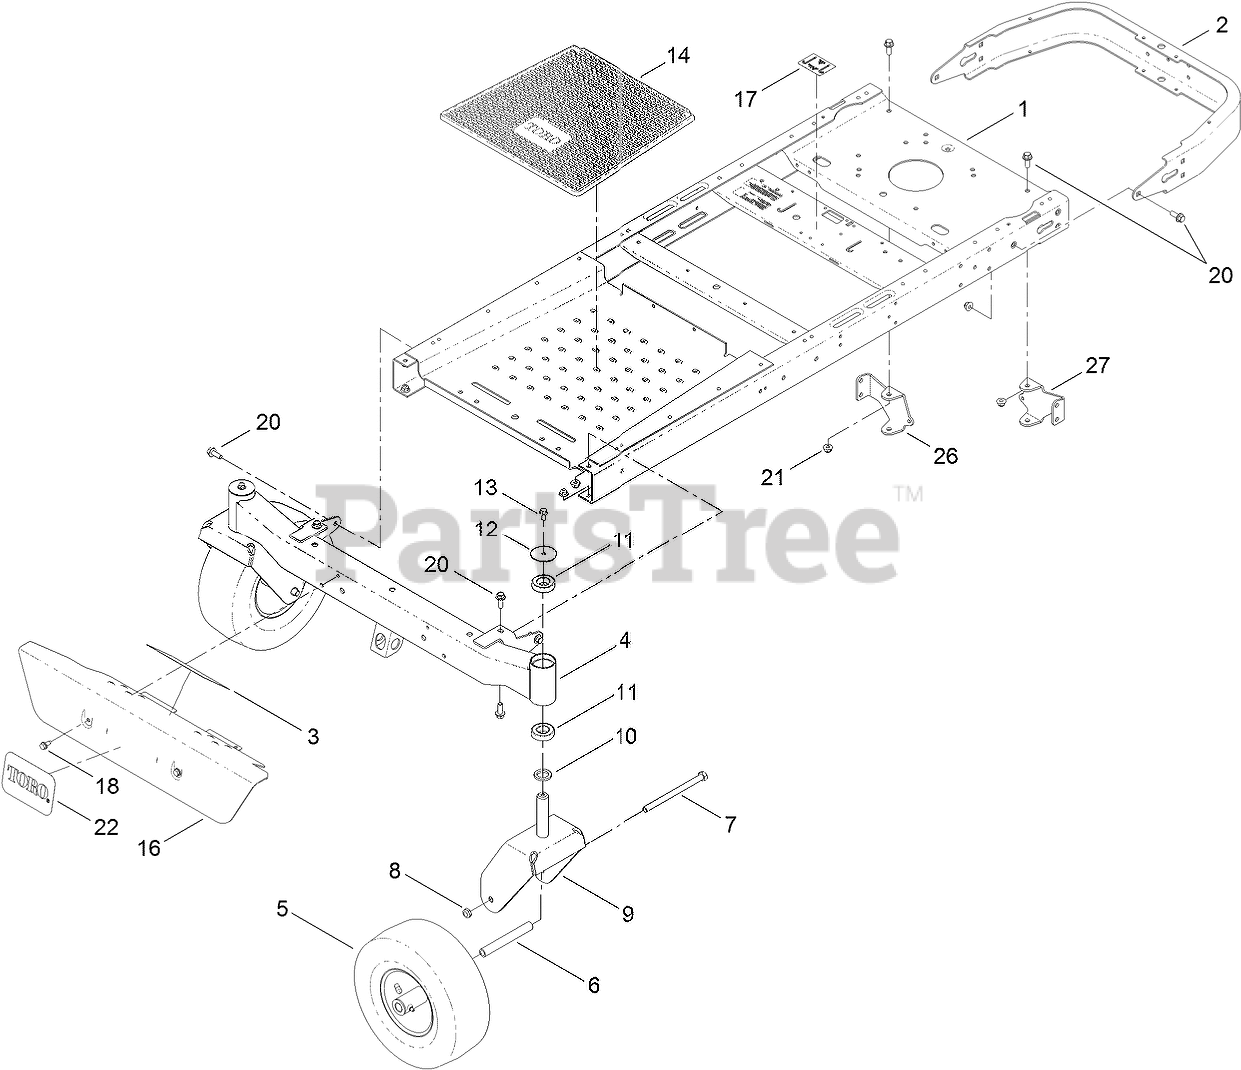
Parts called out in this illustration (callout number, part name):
1	FRAME ASM
2	BUMPER-REAR (WIDE)
3	DECAL-DANGER
4	AXLE-FRONT, WIDE
5	13 INCH WHEEL AND TIRE ASM
6	SPANNER
7	SCREW-HH
8	NUT-LOCK, NI
9	FORK-CASTER
10	WASHER-THRUST
11	BEARING-BALL
12	WASHER
13	SCREW-HHF
14	MAT-FLOOR
16	FOOTREST
17	DECAL-TRANSPORT
18	SCREW-HWHTF
20	SCREW-HHF
21	NUT-HF, NI
22	DECAL
26	MOUNT-HYDRO, REAR (RH)
27	MOUNT-HYDRO, REAR (LH)
